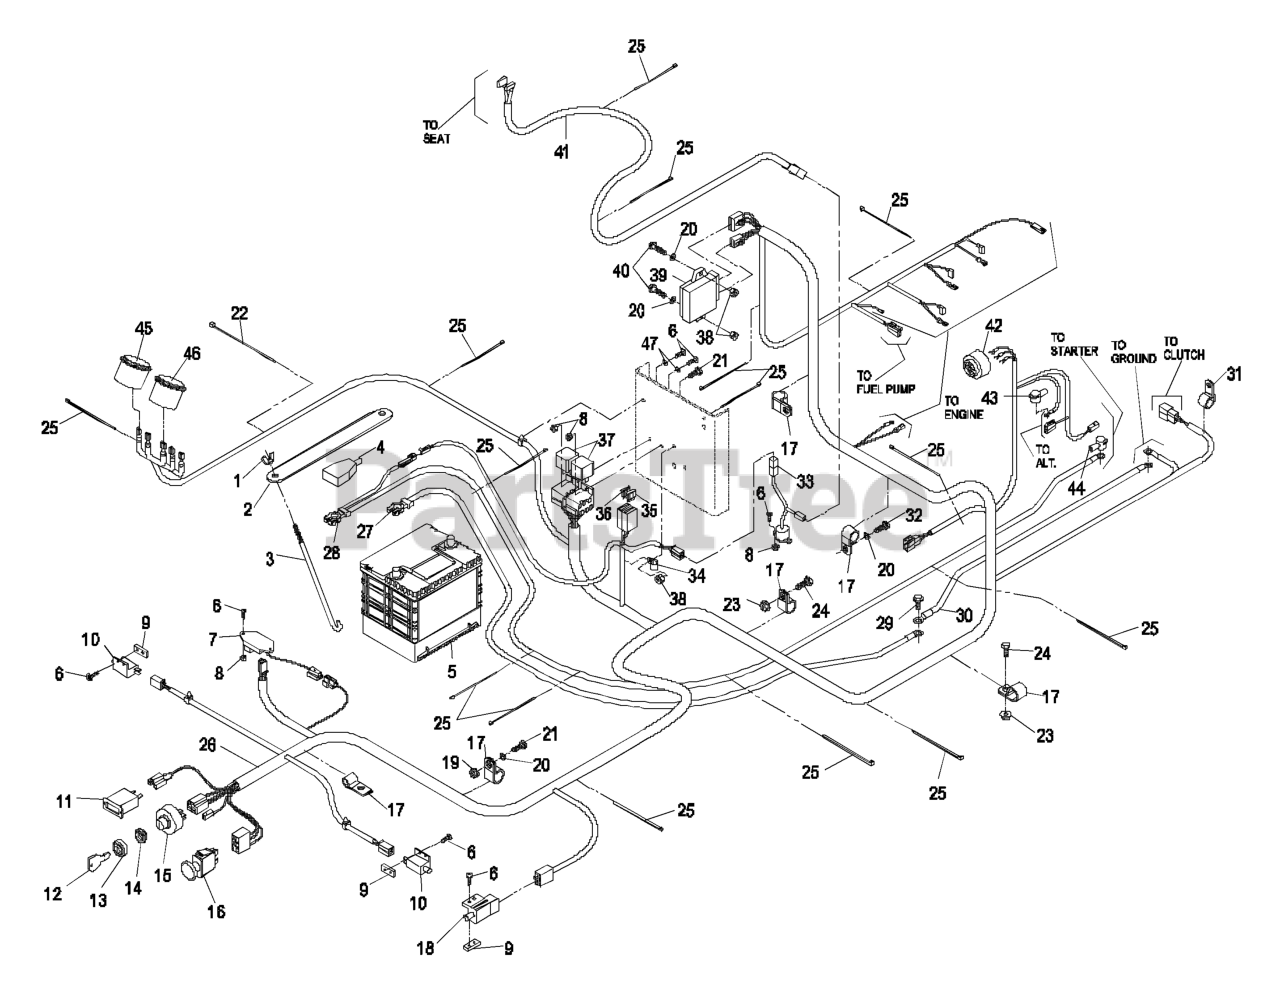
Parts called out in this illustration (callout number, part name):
1	WINGNUT
2	HOLDDOWN-BATTERY
3	BOLT-HOLDDOWN
4	INSULATOR-TERMINAL, BATTE
5	Battery, 12v SAE Post
6	SCREW-PPH
7	MODULE-DELAY, SEAT
8	NUT-LOCK, NI
9	PLATE-TAPPED
10	SWITCH-OPEN, NORMALLY
11	METER-HOUR
12	KEYS-IGNITION (SPARE PAIR
13	SEAL-SWITCH, IGNITION
14	NUT-SWITCH, IGNITION
17	CLIP-LOOM
20	WASHER-FLAT
21	SCREW-HH
22	TIE-PLASTIC
24	SCREW-HH
25	TIE-PLASTIC
27	CABLE-BATTERY NEGATIVE
28	CABLE-STARTER
29	Screw-HWH 5/16-18 X 3/4 Tf
30	CABLE-ENGINE NEGATIVE
31	CLIP-LOOM
34	CLIP-LOOM
35	FUSE-40 AMP
36	FUSE-BLADE TYPE, 20 AMP
38	NUT-LOCK, NI
39	Module, Ignition Processor
40	SCREW-HH
41	HARNESS-WIRING, SEAT
42	ALARM-TONE, DUAL
43	CAP-INSULATOR, RED
44	INSULATOR-STARTER
45	GAUGE-VOLTMETER
46	GAUGE-TEMPERATURE
47	WASHER-FLAT
